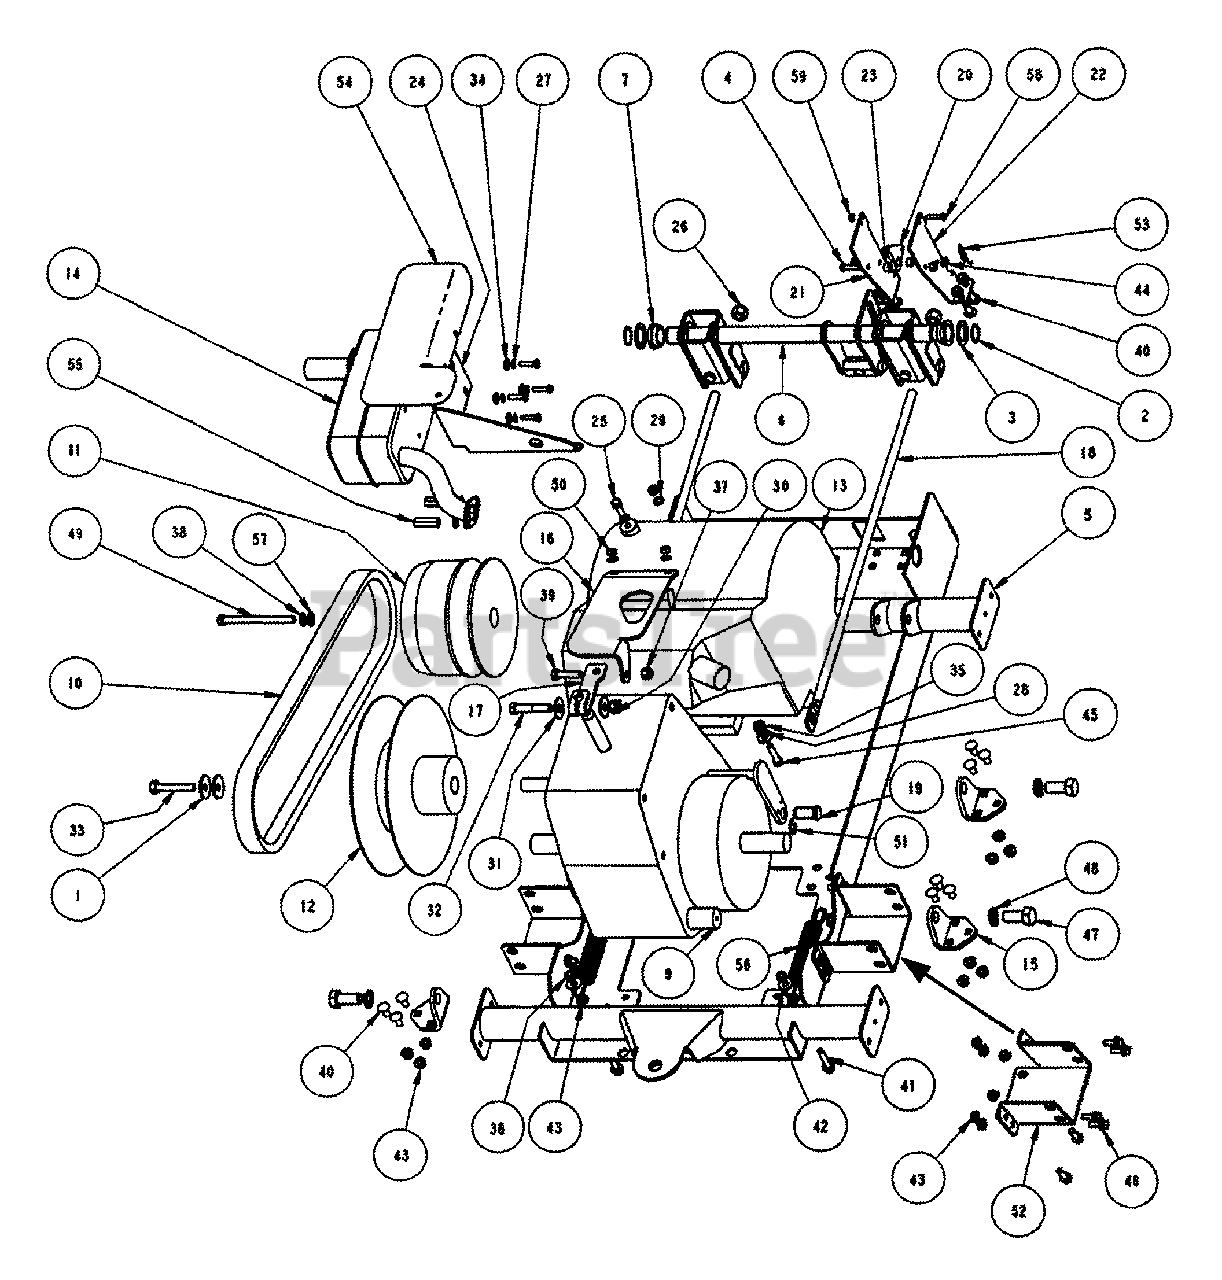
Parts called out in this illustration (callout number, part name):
1	WASHER, CONE
2	EXTERNAL RETAINING RING 1 INCH
3	BUSHING
4	H HCS, 1/4-20 X 1.00 YZ
5	WELDMENT, CVT DRIVE BASE
6	BRAKE ASSEMBLY, UTILITY VEHICLE
7	BEARING, 1 IN. ID
9	TRANSAXLE, TTK35
10	BELT, CVT, 58.122 E.L.
11	CVT DRIVE CLUTCH
12	CVT DRIVE PULLEY
14	MUFFLER
15	BRKT., TRANSMISSION MOUNT
16	BRKT., ENGINE-TRANS. TOURQUE
17	SHIFT ARM, CVT
18	BRAKE ROD, REAR CVT
19	BRAKE ANCHOR PIN
20	PAWL, PARK BRAKE
21	BRKT., LH PARK BRAKE PAWL PIVOT
22	BRKT., RH PARK BRAKE PAWL PIVOT
23	SPACER, PARK BRAKE
24	MUFFLER MOUNTING BRACKET
25	M8-1.25 X 18, HEX SEMS
26	NUT, 1/2-20, LIGHT, NYLOCK
27	SPLIT LOCK WASHER, 1/4
28	WASHER, 5/16 SPLIT LOCK
29	ETLW, 5/16
30	HTLN, 7/16-20
31	WASHER, 1/4 X 1 X .065
32	H HCS, 7/16-20 X 2-1/4
33	M10-1.5 X 60 HHCS
34	WASHER, .28 X .63 X .06 GR5YZ
35	HEX NUT, 5/16-24 YZ
36	HEX NYLON INSERT NUT 5/16-18 YZ
37	HNYL, 3/8-16, YZ
38	SLW, .38 X .68 X .09 YZ
39	H HCS 3/8-16 X 1-1/2 GR5 YZ
40	RHSSNB, 5/16-18 X 3/4 GR5 YZ
41	HFLB, 5/16-18 X 1.50 YZ
42	WASHER, .375 X .875 X .083
43	FLN 5/16-18 YZ
44	1/4-20 HEX NYLON INSERT NUT
45	H HCS, 5/16-24 X 1-1/2
46	HFLB, 5/16-18 X 7/8-YZ
47	HHCS, 1/2-13 X 5.00
48	16mm SLW, YZ
49	HHCS, 3/8-24 X 4.50 YZ
50	HEX NUT, M8 X 1.25, YZ
51	RETAINING RING 5/8
52	CHANNEL, SUBFRAME CONNECT
53	SPRING, EXT. PAWL RETURN
54	HEAT SHIELD
55	HEX NUT, M8-1.25, YZ SPECIAL
56	SPRING, BRAKE RETURN
57	WASHER, SAEW 3/8 FLAT
58	HWST, #10-32 X 1.00
59	HEX CENTER LOCK NUT, #10-32
